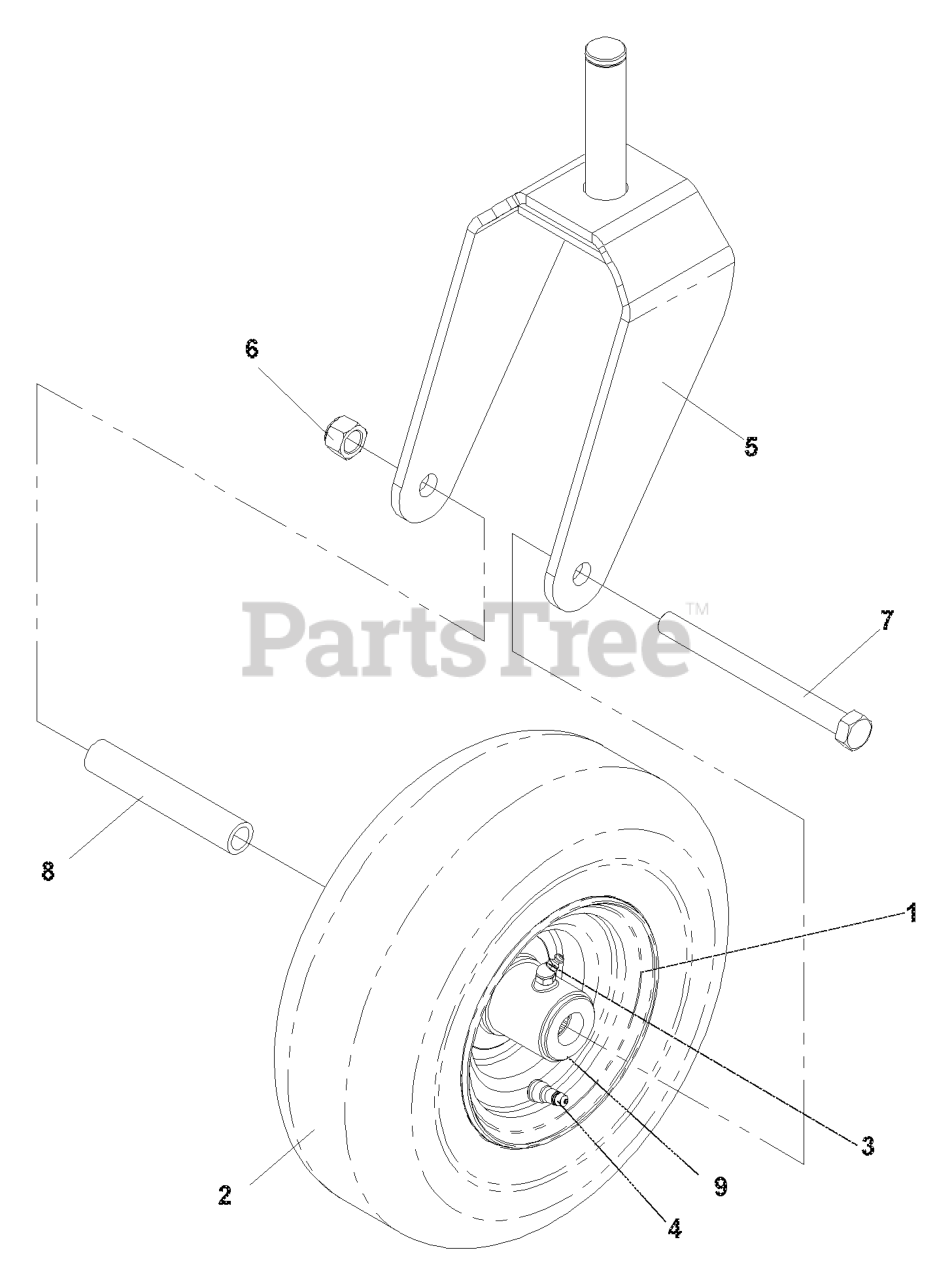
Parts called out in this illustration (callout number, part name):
2	TIRE - CASTER
3	ZERK
4	VALVE STEM TR-412
5	CASTER WLDT
6	NUT 1/2-13 HEX NYLOC ZD
7	HCS 1/2C X 5 1/2
9	BEARING RETAINER
